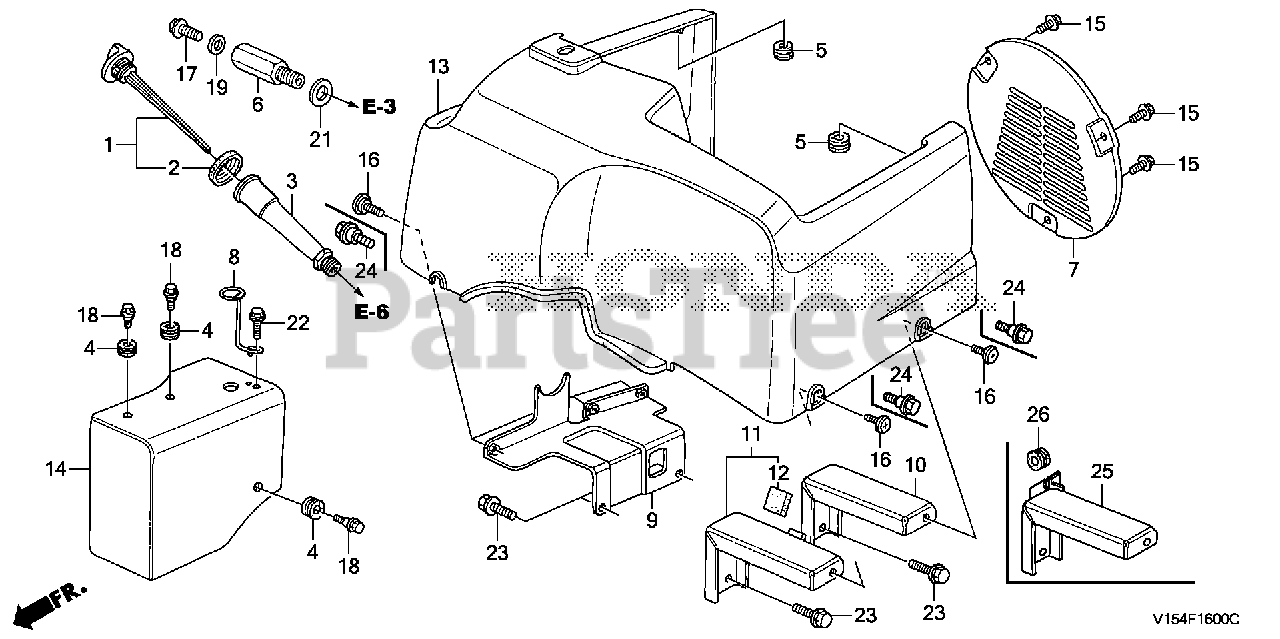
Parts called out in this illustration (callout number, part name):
1	CAP ASSY., OIL FILLER
2	GASKET, OIL FILLER CAP
3	EXTENSION, OIL FILLER
4	RUBBER, CANISTER MOUNTING
5	GROMMET, RESERVE TANK
6	EXTENSION, OIL DRAIN
8	GUIDE, CABLE
9	STAY, R. FR. COVER
11	STAY B, L. FR. COVER
12	RUBBER, STOPPER
13	COVER, FR. *R280* (POWER RED)
14	COVER, CHUTE MOTOR
17	BOLT, DRAIN PLUG
18	BOLT, RADIATOR SETTING
19	WASHER, DRAIN PLUG (10.2MM)
21	WASHER, DRAIN PLUG (12MM)
22	BOLT, FLANGE (6X16)
23	BOLT, FLANGE (8X16)
24	BOLT, SPLASH GUARD
25	STAY A, L. FR. COVER
26	RUBBER, SCREEN SETTING
